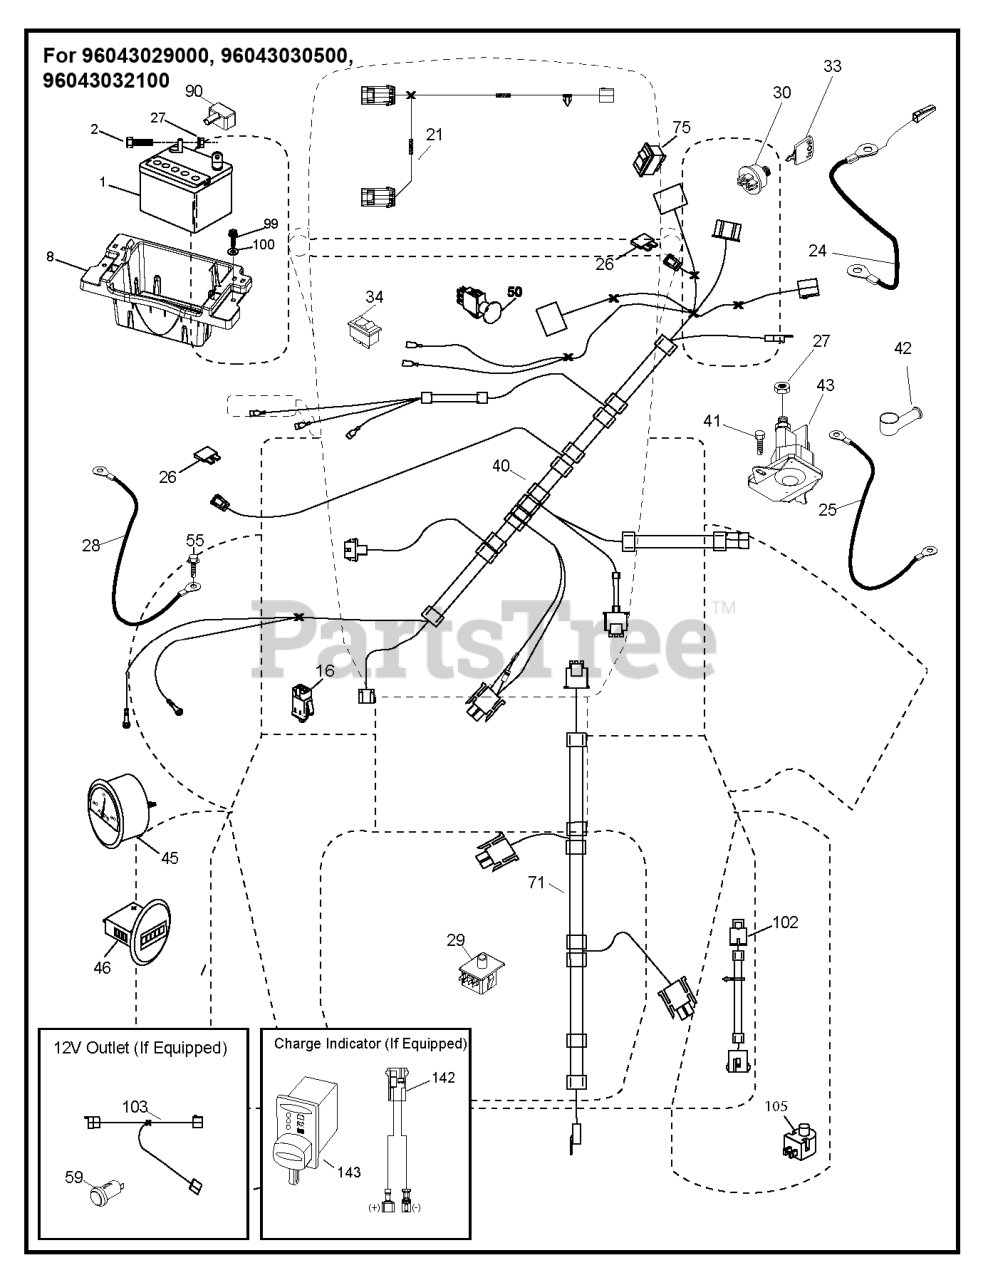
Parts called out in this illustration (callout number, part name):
1	BATTERY.DRY.30.AMP
2	BOLT.HEX.1/4.X.3/4.DICHROMATE
8	TRAY.BATTERY BOX.FRONT
16	SWITCH INTERLOOK PUSH-IN
21	HARNESS LIGHT ASSY TRACTOR,
24	CABLE.FRBATT.W/WIRE.8GA.8
25	CABLE.STARTER.8GA.17.5
26	FUSE 20AMP
27	NUT HEX_LRG FLG_1_4-20_LOCK
28	CABLE.GROUND.21"BLK.8GA.90T
29	SWITCH.SEAT.DP W/RAMPS
30	SWITCH.IGN.DELTA.W.LGH.ROS
33	KEY.CHAIN.BLISTER.PACK.GEN.INT
40	HARNESS.DASH.EDIFF.RND.CHG
42	COVER.TERMINAL.RED
50	SWITCH.PTO.8TERMINAL.STD.BLK
55	BOLT.5/16-18UNCX3/4 W/SEMS.BLK
71	HARNESS.IGN.CHASSIS.TEX.DCKLOC
75	SWITCH.ON/OFF.(DIFF.LOCK)
90	COVER.TERMINAL.BATTERY
99	SCREW HEXWSHR 1/4-20X3/4
102	HARNESS PIGTAIL PCH TEX ROS
103	HARNESS.PIGTAIL.12V.OUTLET.
105	REVERSE SWITCH
